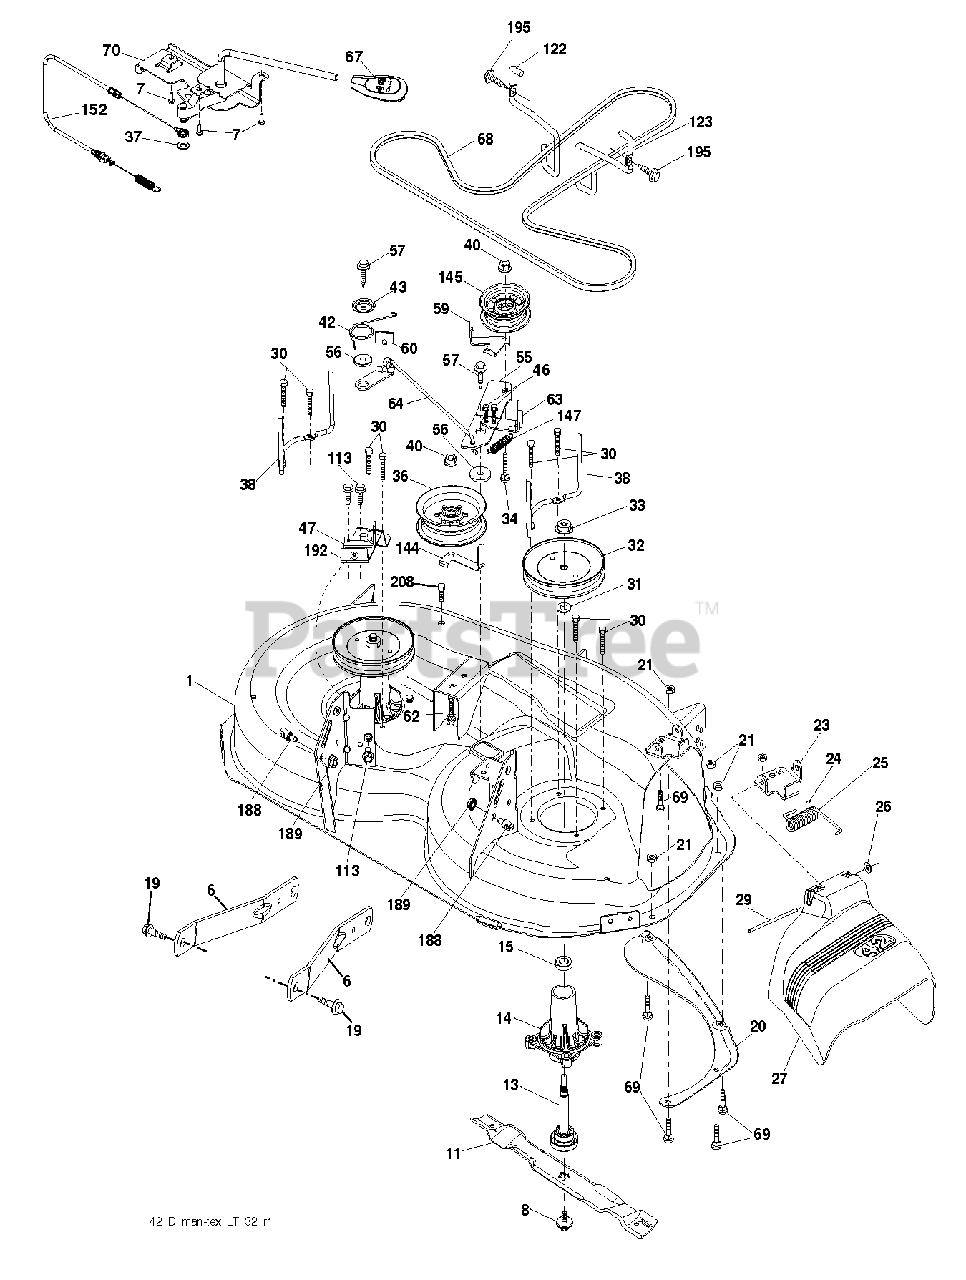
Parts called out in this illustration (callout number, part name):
1	KIT.SVC.42"199911X431
6	ARM.SUSPENSION.MOWER.R
7	SCREW.#10 X 0.750.BOS
8	BOLT.WASHER.ASM.7/16-2
11	42" HI-LIFT BLADE
13	SHAFT.ASM.MDRL.N/GREASE.38
14	HOUSING.MANDREL.4PT.
19	BOLT.SHOULDER
20	BAFFLE.VORTEX
21	LOCKNUT
23	BRKT.DEFLECTOR.38"2005+
24	CAP-SLEEVE LT
25	SPRING.TORSION.DEFLECT
26	NUT PUSH M
27	SHIELD.DEFLECTOR.MOWER.42"BLAC
29	ROD.HINGE
30	SCREW, WASHER HEAD
31	WASHER.SPACER.MANDREL
32	PULLEY.MANDREL.5.438.PD
33	NUT.FLANGE.LOCK.TOP
34	BOLT.3/8-16X1.50
36	PULLEY.IDLER.2006
37	WASHER
38	KEEPER.BELT.MANDREL.PULLEY
40	NUT LOCK FLG 3/8-16 UNC
42	SPRING.TORSION.BRAKE
43	SRPING.TORSION.RETAINE
46	SCREW.1/4-20X5/8
47	BRKT.CLUTCH.CABLE
55	IDLER.ARM.42"
56	SPACER.RETAINER
57	SCREW 3/8-16X1
59	GUARD, BELT
60	ARM BRAKE MOWER
63	ARM BRAKE MOWER
64	LINK BRAKE
67	HANDLE.CLUTCH.CABLE.LT
68	BELT.DECK.DRIVE.42"
69	BOLT
70	CLUTCH.ASM.MANUAL.LT.PRED
113	BOLT.5/16HEX.WHS.HD
122	KEEPER BELT ENGINE LH
123	KEEPER BELT RH
144	KEEPER.BELT.MOWER
145	PULLEY.IDLER.48"PRIMARY
147	RETURN SPRING
152	CABLE.CLUTCH.MANUAL.
188	STUD.FASTNER.W/ANTI-ROTATE
189	NUT LOCK HEX FLANGE 5/16-18
192	BRKT.BRAKE.STAND.LH.
195	SCREW, 3/8-16X3/4
208	SCREW 3/8-16X1/2
